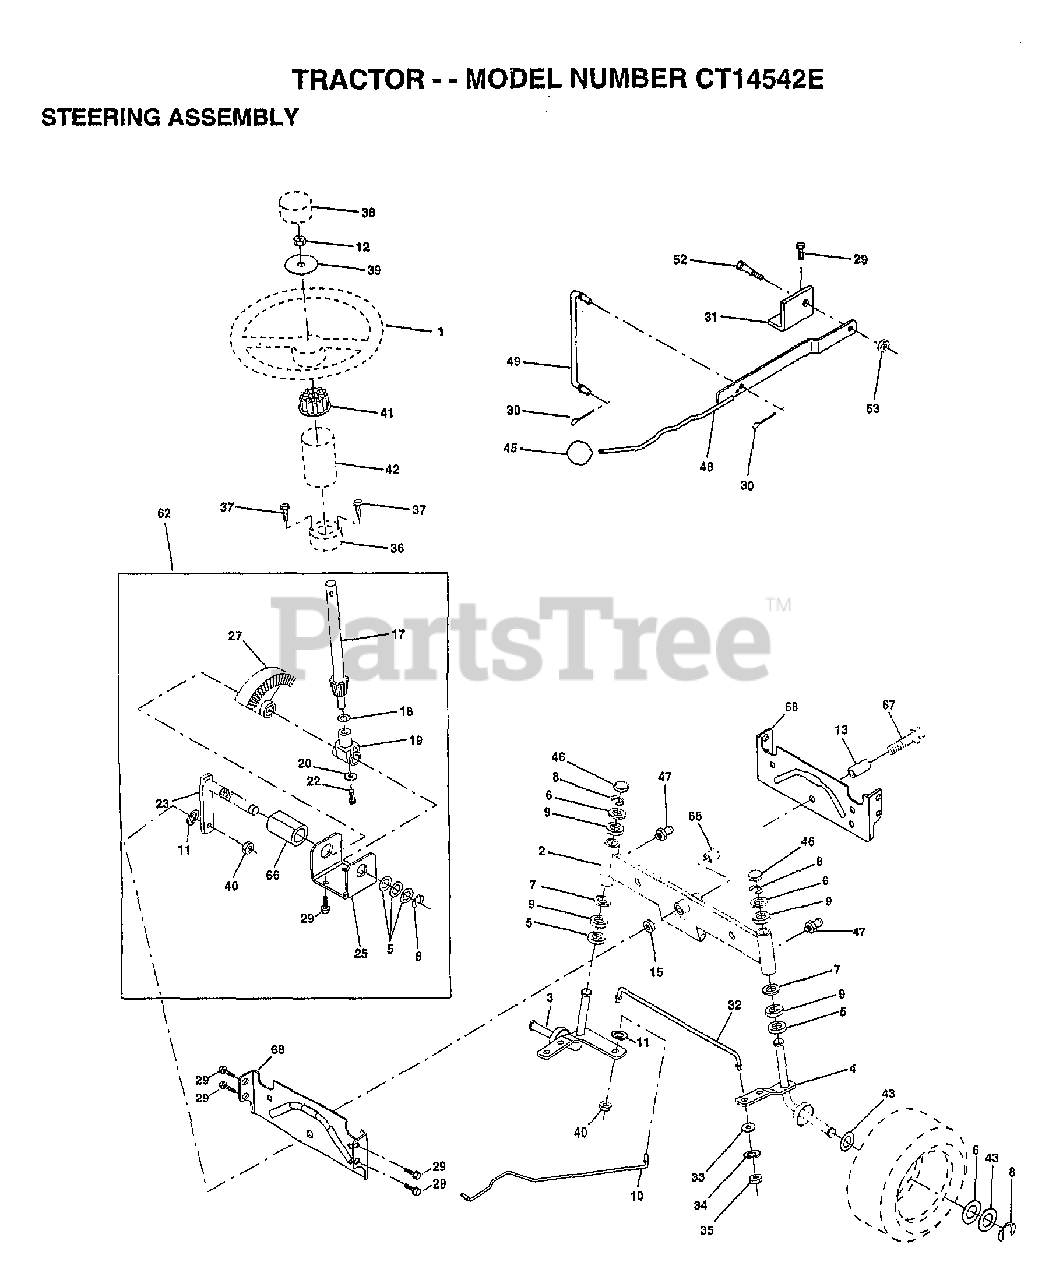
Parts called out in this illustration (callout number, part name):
1	WHEEL STR AYP BLK
2	AXLE ASM
3	SPINDLE.ASM.LH
4	"SPINDLE ASM,RH"
5	WASHER .T
6	WASHER
7	WASHER
8	RING
9	COL. SRTG. BEAR.
10	DRAGLINK-STAMPED
11	LOCKWASHER
13	BEARING AXLE
15	"NUT-LOC,FLANGE LT"
17	SHAFT ASM STEERNG
18	THRUST WASHER
19	SUPPORT.SHAFT
21	LOCKWASHER
22	SCREW HEX SOC1/4-
25	BRKT-STEERING
27	GEAR SECTOR
29	SCREW
30	COTTER PIN
31	BRKT.PVT.MAN.LVR.
32	ROD.TIE.19.75
33	WASHER M
34	LOCKWASHER
35	NUT.LOCK.5/16-24
36	BUSHING.STRG.3/4
37	"SCREW-TT,10-32 FL"
38	CAP STEER AYP
39	WASHER
40	GRIPCO NUT
41	ADAPTER LT
42	BOOT SHAFT STEER
43	WASHER
45	KNOB T (1/2-HOLE)
46	CAP
47	ZERK M
48	LEVER.ASM.CLUTCH
49	LINK CLTCH W/NUTS
52	"BOLT, SHOULDER LT"
62	KIT STEERING ASM
65	SPACER AXLE
66	"BEARING-ARM,PITMA"
67	BOLT
68	BRACE AXLE
